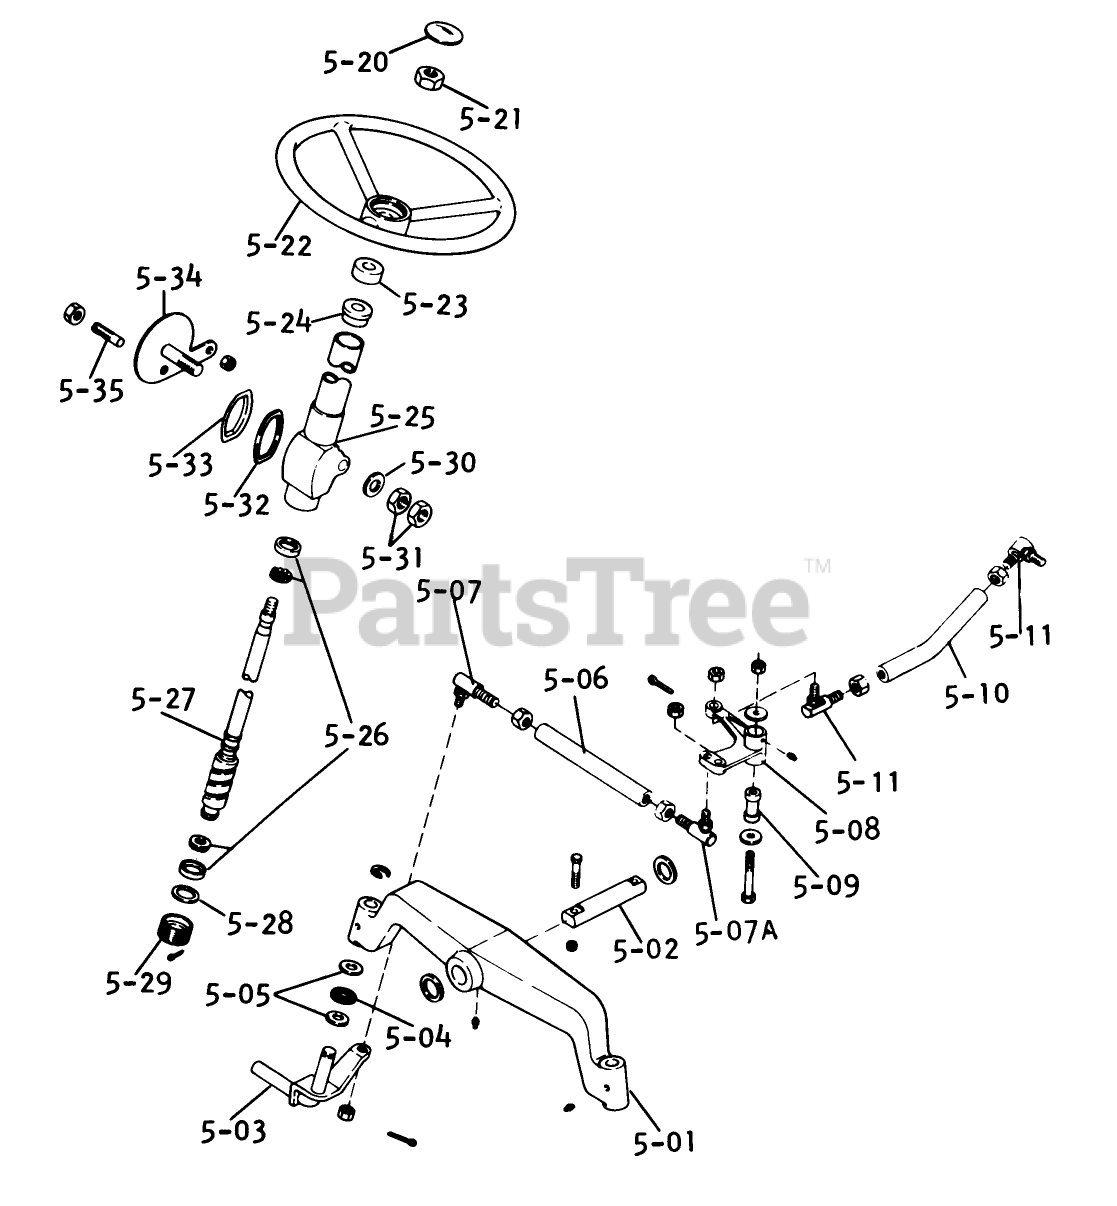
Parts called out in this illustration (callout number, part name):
5-01	Axle Front
5-02	PIN AXLE
5-03	Spindle Assembly R.H.
5-04	BEARING-THRUST
5-05	WASHER-THRUST
5-06	TIE ROD R
5-07	Ball Joint RH
5-07A	LH BALL JOINT R
5-08	Bellcrank-steering
5-09	Bushing
5-10	Drag Link
5-11	BALL JOINT-SHORT R
5-20	STEERING WHEEL INSE
5-21	Nut
5-22	Steering Wheel
5-23	Cover-Dust
5-24	Column Bearing
5-25	Assy-Housing and Column
5-26	BALL CUP KIT
5-27	Steering Gear
5-28	WASHER
5-29	Adjusting Plug
5-30	Washer 49/64 X 1 1/4
5-31	Nut
5-33	Retainer-Seal
5-34	Lever
5-35	Stud
